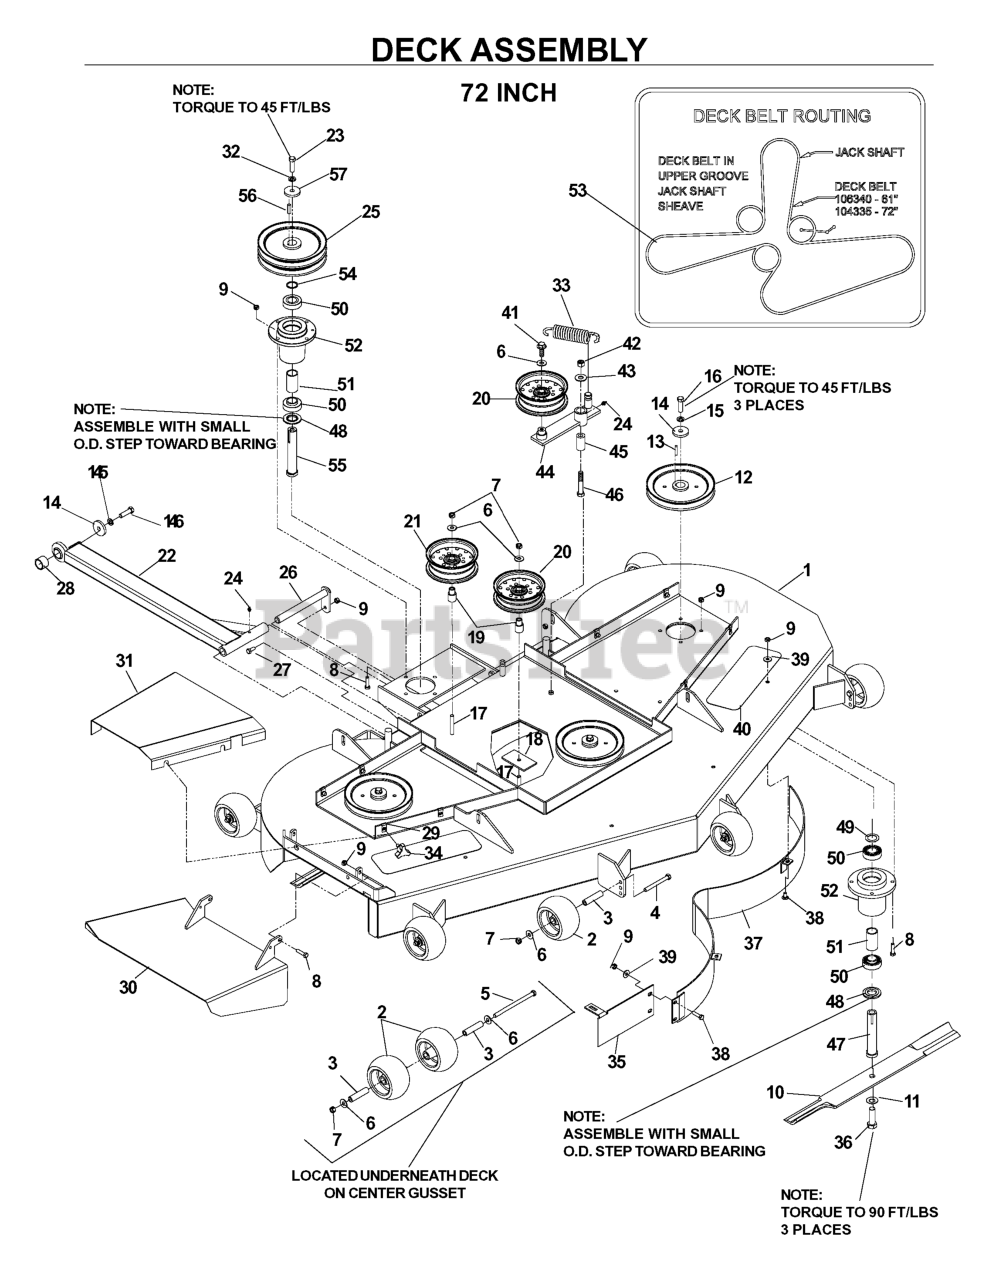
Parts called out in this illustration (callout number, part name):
1	DECK W/DECALS 72" HUS
2	ANTI-SCALP ROLLER
4	HCS 3/8C X 3 1/2
5	BOLT 3/8 X 6" GRD 8
6	WASHER 3/8 FLAT
7	NUT 3/8C CENTERBLOCK
8	HCS 5/16C X 1 1/4
9	NUT 5/16C CENTERLOCK
10	BLADE OEM - 25"
11	BELLEVILLE SPRING WASHER
13	KEY 1/4 SQ X 1 1/8
14	SPINDLE WASHER
15	WASHER 7/16 LOCK
16	HCS 7/16F X 1 1/2
17	HCS 3/8C X 3
18	SUPPORT PLATE
19	IDLER BUSHING
20	IDLER PULLEY
21	IDLER PULLEY (TALL)
22	STRUT WELDMT - R.H
23	HCS 7/16F X 1 1/2
24	ZERK
25	SHEAVE WSL
26	PIN WELDMENT
27	HCS 5/16C X 3/4
28	SPACER, STRUT
29	U-CLIP 5/16-18 NUT RETAINER
30	DISCHARGE CHUTE
31	BELT SHIELD RH ORANGE
32	WASHER 7/16 LOCK
33	DECK SPRING
34	KNOB W/STUD
35	BAFFLE/CENTER-FLAT BLK
36	HEX SCREW-5/8F X 2 GR8
37	BAFFLE/CENTER-CURVED
38	CARRIAGE BOLT 5/16C X 5/8"
39	WASHER 5/16 FLAT
40	ANTI-SKID PAD
41	4CS 3/8C X 1 SERRATED HEAD
42	NUT 1/2-13 HEX NYLOC ZD
43	WASHER 1/2 FLAT
45	PIVOT BUSHING
46	HCS 1/2C X 3 1/4
47	SPINDLE SHAFT
48	COMBO SPACER
49	BUSHING.MACHINE.18.GAUGE
50	BEARING
52	HOUSING, DIE CAST
53	BELT, DECK
54	BUSHING.MACHINE.18.GAUGE
55	SPINDLE SHAFT
56	KEY 1/4 SQ X 1 1/8
57	SPINDLE WASHER
539105566	BELT SHIELD LH ORANGE
539107751	STRUT WELDMT, L.H.
